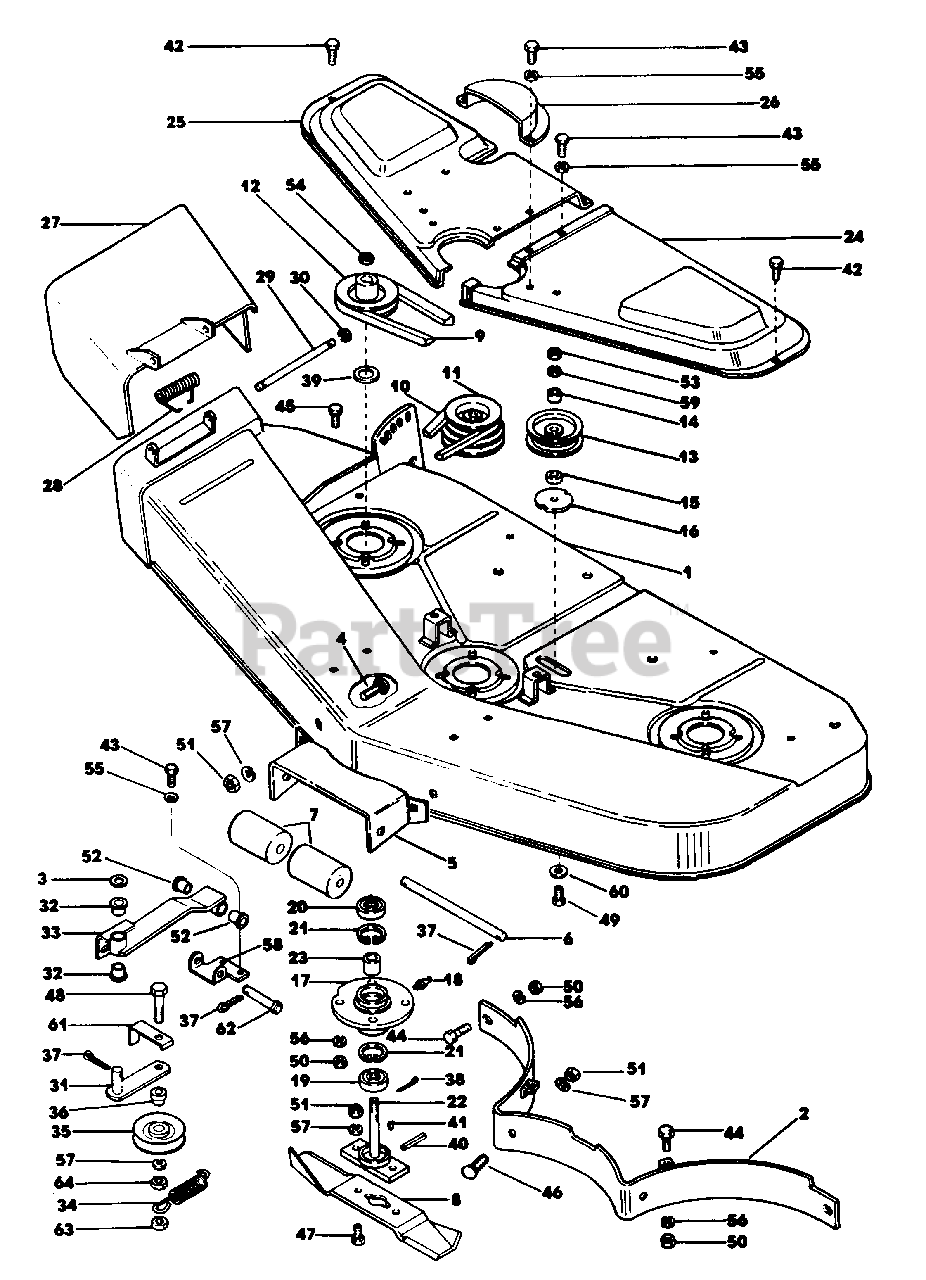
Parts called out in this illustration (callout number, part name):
1	Cutter Housing & Decal Assembly
2	Baffle Assembly
3	Washer Special
4	Bolt, Carriage 3/8-16 x 3/4 Plated
5	Bracket, Roller
6	Shaft, Roller
7	Roller
8	Blade
9	V-Belt, Deck
10	V-Belt, Drive
11	Pulley, Drive
12	Pulley, Blade Spindle
13	Pulley, Idler
14	Spacer
15	Spacer
16	Washer
17	Spindle Housing
18	Grease Fitting
19	Bearing
20	Bearing
21	Ring, Snap
22	Spindle Assembly
23	Sleeve
24	Cover Assembly-L.H.
25	Cover Assembly-R.H.
26	Guard, Drive Belt
27	Chute Extension Assembly
28	Spring Chute
29	Shaft, Chute
30	"E" Ring
31	Idler Arm Assembly
32	Bushing
33	Idler Pivot Assembly w/Bushings
34	Spring Idler Arm
35	Pulley, Idler Arm
36	Spacer
37	Pin Cotter 1/8 x 3/4 Plated
38	Pin Cotter 1/8 x 1-1/2 Plated
39	Washer
40	Pin, Roll 5/32 x 1-1/2 Grade 5
41	Key, Woodruff 3/16 x 3/4
42	Thread Forming Screw, Hex Hd. 1/4-20 x 1/2
43	Cap Screw, Hex Hd. 1/4-20 x 1/2 Plated, Grade 5
44	Cap Screw, Hex Hd. 5/16-18x 3/4 Plated, Grade 5
45	Cap Screw, Hex Hd. 5/16-18 x 1" Plated, Grade 5
46	Bolt, Carriage Short Neck 3/8-16 x 3/4
47	Cap Screw, Hex Hd. 3/8-16 x 1" Plated, Grade 5
48	Cap Screw Hex Hd. 3/8-16 x 1-7/8 Plated, Grade 5
49	Cap Screw, Hex Hd. 5/8-11 x 2" Plated, Grade 5
50	Nut, Hex 5/16-18 Plated
51	Nut, Hex 3/8-16 Plated
52	Bushing
53	Nut, Hex Jam 5/8-11 Plated
54	Nut, Hex Slotted 3/4-16
55	Washer, Spring Lock 1/4 Plated
56	Washer, Spring Lock 5/16 Plated
57	Washer, Spring Lock 3/8 Plated
58	Idler Pivot Bracket
59	Washer, Spring Lock 5/8 Plated
60	Washer, Flat SAE 5/8 Plated
61	Belt Guide
62	Clevis Pin-Pivot
63	Nut, Hex Self Locking 3/8-16 Plated
64	Nut, Hex Jam 3/8-16 Plated
